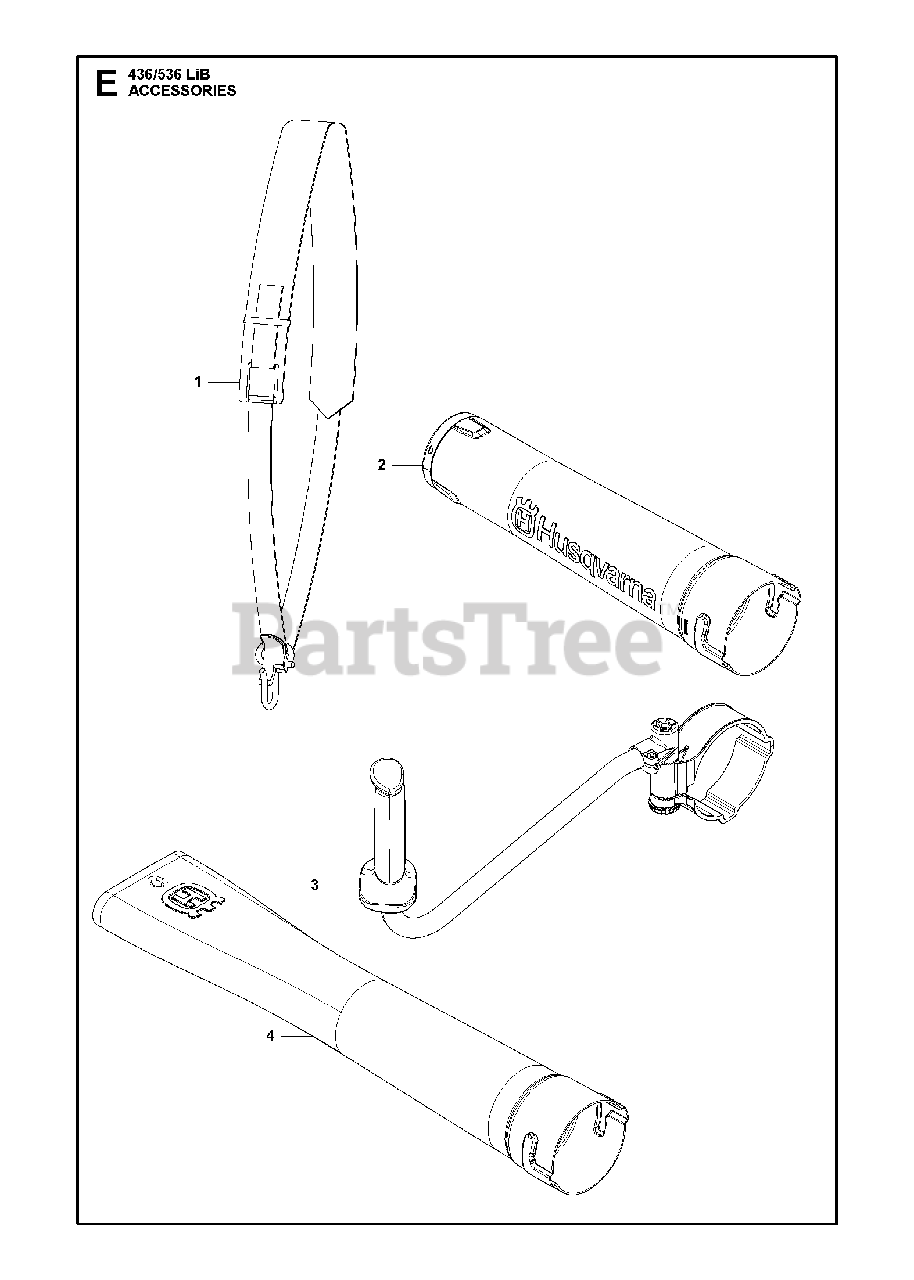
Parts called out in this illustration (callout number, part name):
1	STRAP
2	TUBE ASSY NOZZLE 536LIBX
4	BLOWER NOZZLE FOR 320
